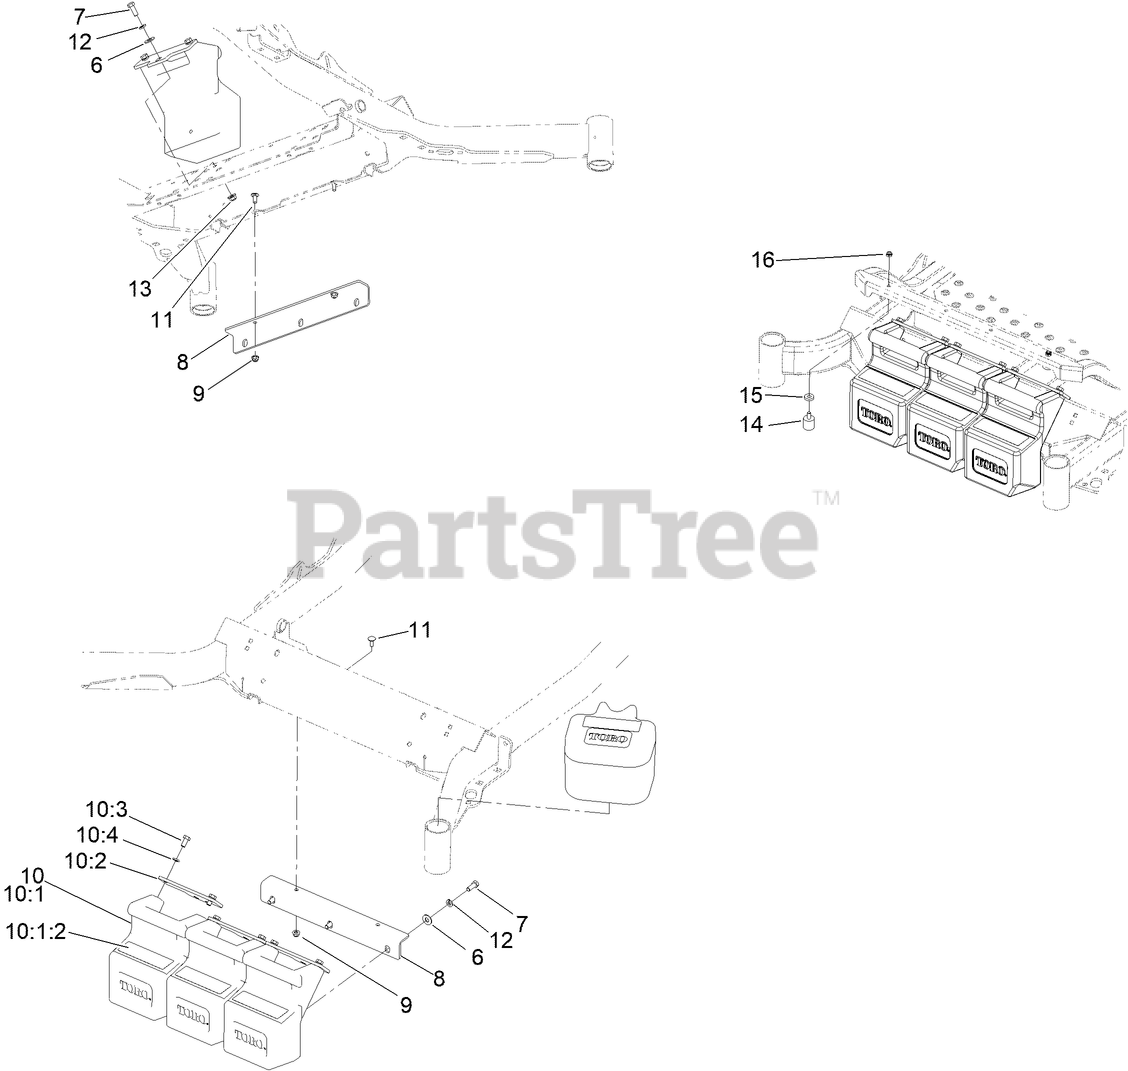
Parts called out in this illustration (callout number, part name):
6	WASHER-FLAT
7	SCREW-HH
8	BRACKET-MOUNT, WEIGHT
9	NUT-HF, NI
10	WEIGHT ASM
10:1	WEIGHT W/DECAL ASM
10:1:2	DECAL-WARNING, COUNTERWEIGHT
10:2	TAB-SUPPORT, WEIGHT
10:3	SCREW-HH
10:4	WASHER-LOCK
11	SCREW-CARR
12	WASHER-LOCK
13	NUT-HF, NI
14	BUMPER-RUBBER
15	SPACER
16	NUT-LOCK, NI
